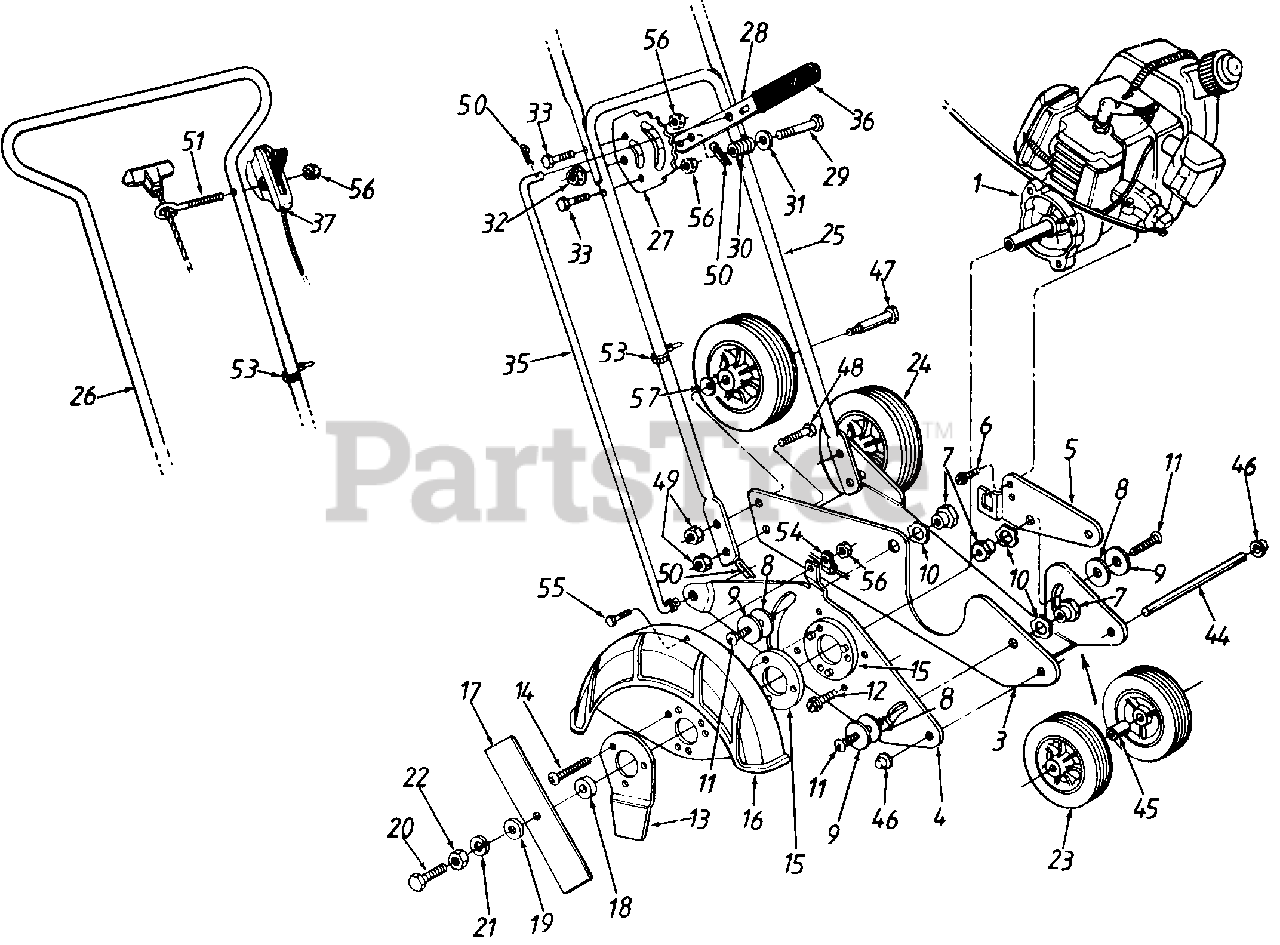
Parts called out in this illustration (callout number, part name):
1	ENGINE
3	EDGER BASE
4	SIDEPLATE
5	ENGINE 0 SUPPORT BRKT.
6	HEX WASH. HD. SCR. #8-32 X .625"
7	SHLD. NUT 5/16-18 THD.
8	THRUSH WASH. .319" I.D. X 1.25" O.D. X .05
9	FL-WASH. .319" I.D. X 1.25" O.D. X .048"
10	WAVE-WASH. .53" X.78" X.013"
11	TRUSS MACH. SCR. 5/16-18 X .75" LG.
12	HEX WASH. HD. SCR. 1/4-20 X .50" LG.
13	EDGE 0 GUIDE
14	TRUSS MACH. SCR. #10-32 X 1.0" LG.
15	SPACER-BLADE GUARD
16	BLADE GUARD
17	BLADE
18	SPACER .39" I.D. X 1" O.D. X .375"
19	WASHER .406" I.D. X .812" O.D. X .125"
20	HEX BOLT 3/8-24 X 1.5 LG.-GR. 5
21	L-WASH. 318" I.D. (H.D.)
22	HEX NUT 3/8-24 THD.
23	5" WHEEL
24	6" WHEEL
25	LOWER HANDLE
26	UPPER HANDLE
27	RATCHET PLATE
28	RATCHET PLATE HANDLE
29	HEX BOLT 5/16-18 X 1.5" LG.
30	SPRING .5" I.D. X .75" O.D. X 1" LG.
31	FL-WASH. .349" I.D. X .879" O.D. X .063"
32	FLANGE 0 TOP L-NUT 5/16-18 THD.
33	HEX BOLT 1/4-20 X 1.375" LG.
33	NYLON TOP L-NUT 5/16-18 THD.
35	DEPTH CONTROL ROD
36	VINYL GRIP
37	CONTROL CHOKE ASS'Y.
44	AXLE TUBE
45	SPACER
46	PUSHNUT RETAINER
47	SHLD. BOLT .50 DIA. X 1.7"
48	HEX BOLT 3/8-16 X .75" LG.
49	FLANGE L-NUT 3/8-16 THD.
50	COTTER PI
51	ROPE GUIDE EYEBOLT
53	CABLE TIE
54	CLAMP
55	HEX BOLT 1/4-20 X .5" LG.
56	HEX INS. L-NUT 1/4-20 THD.
57	BELL-WASH. .38" I.D. X . 88" O.D.
